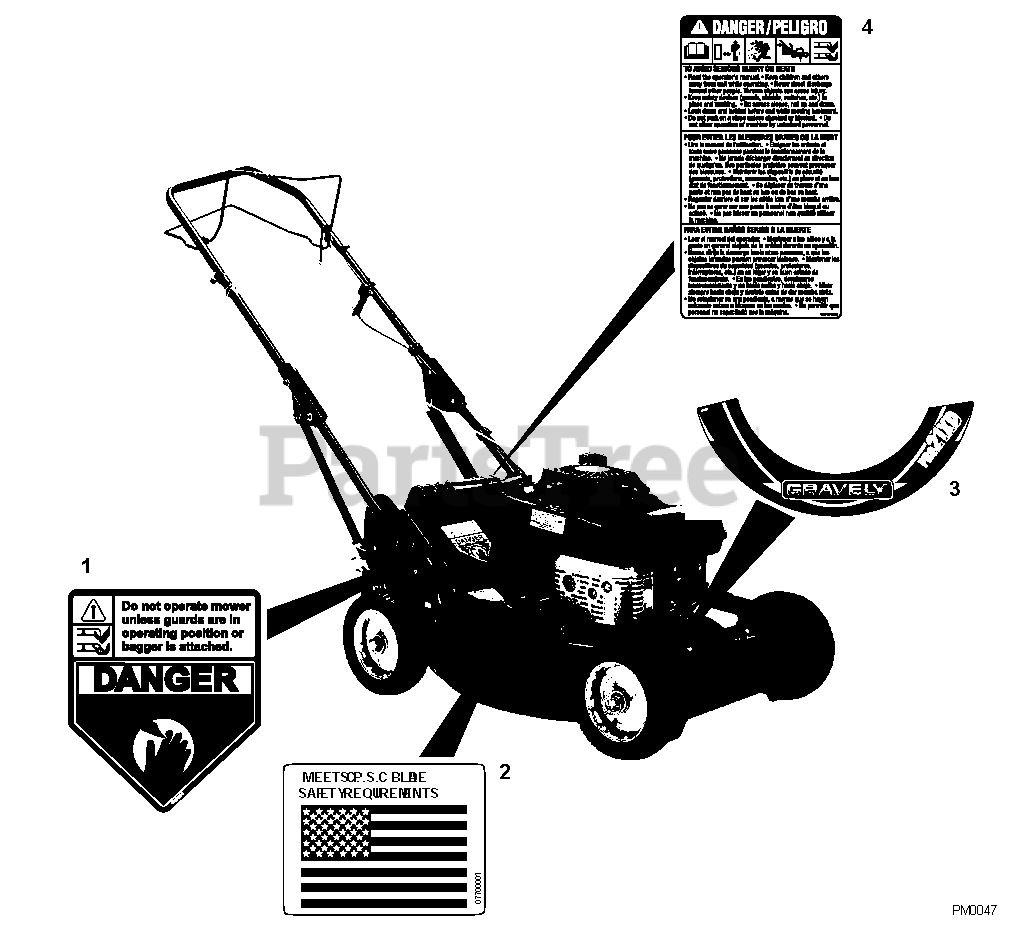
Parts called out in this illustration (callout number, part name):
1	Decal, CPSC Danger
2	Decal, CPSC/USA Flag
3	Decal, PRO21 XD Gravely
4	Decal, Bilingual Danger
